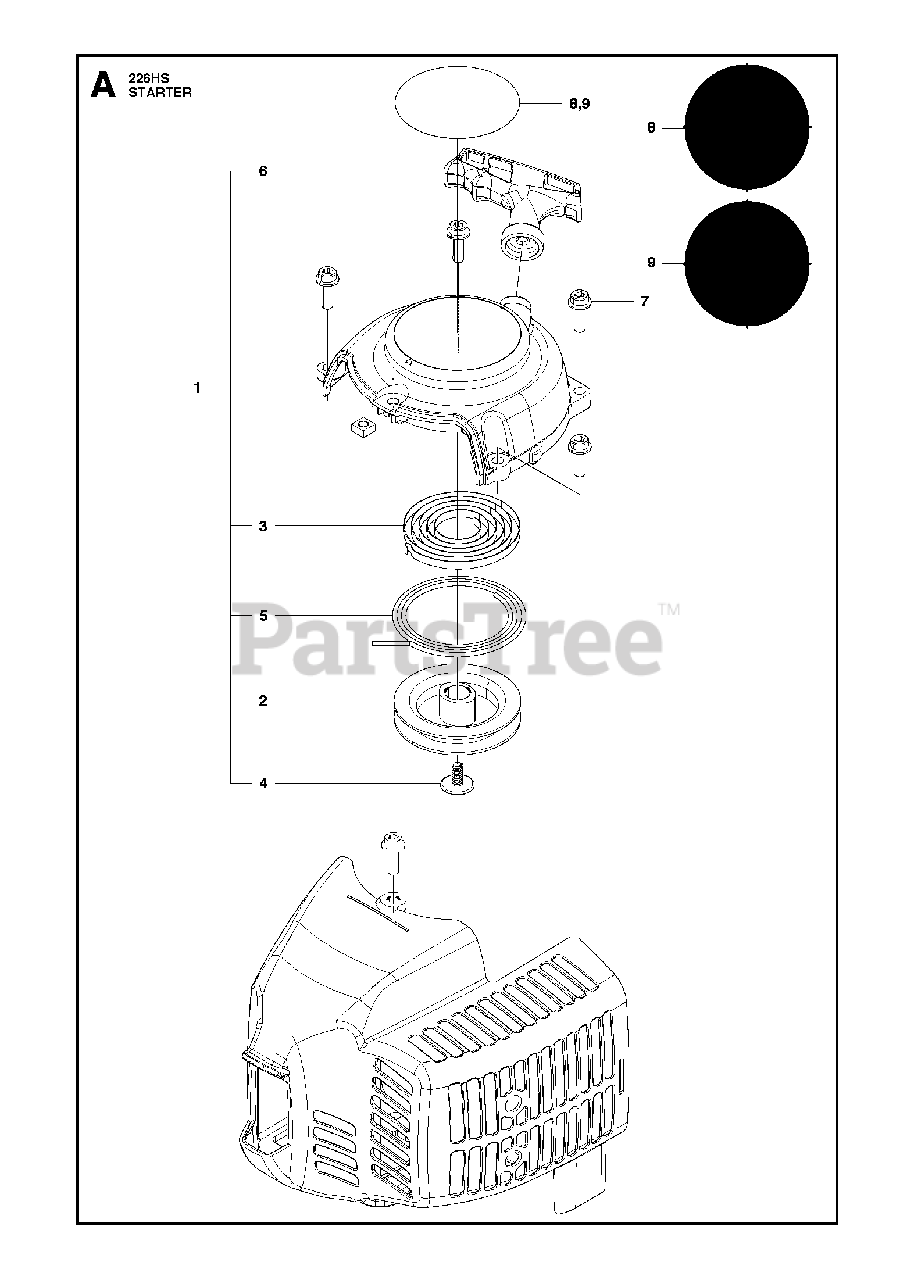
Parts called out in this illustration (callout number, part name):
1	RECOIL ASSY
2	REEL
3	SPRING
4	SCREW
5	ROPE
6	KNOB
8	LABEL,RECOIL
9	LABEL,RECOIL
